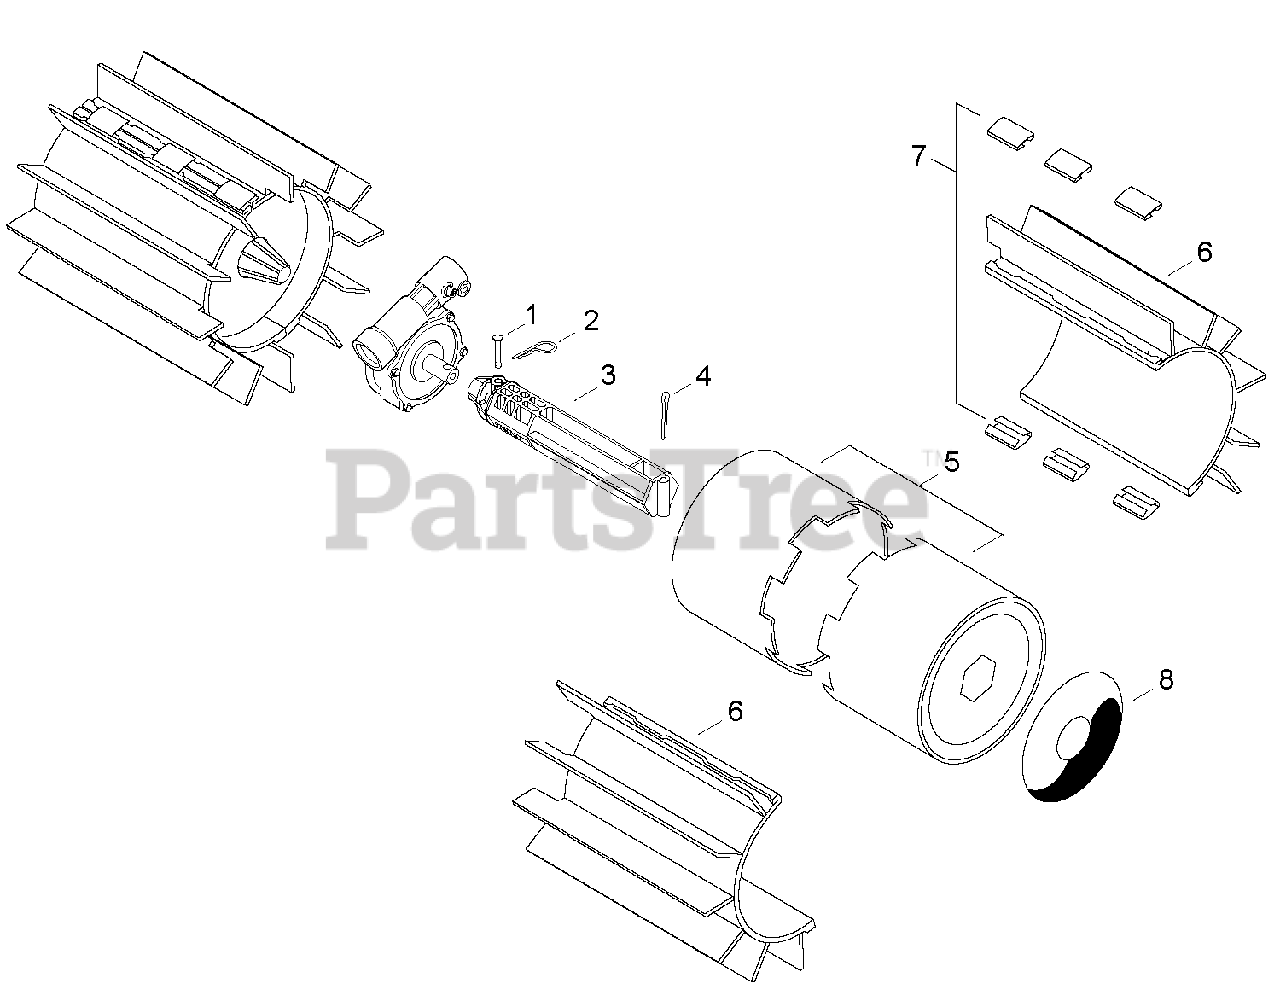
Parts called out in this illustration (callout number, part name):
1	PIN - CLEVIS
2	PIN - HITCH
3	AXLE, DRUM
4	PIN, SPLIT
6	BELT, SWEEPER
7	CLIP, BELT
8	LABEL - POWERBROOM
